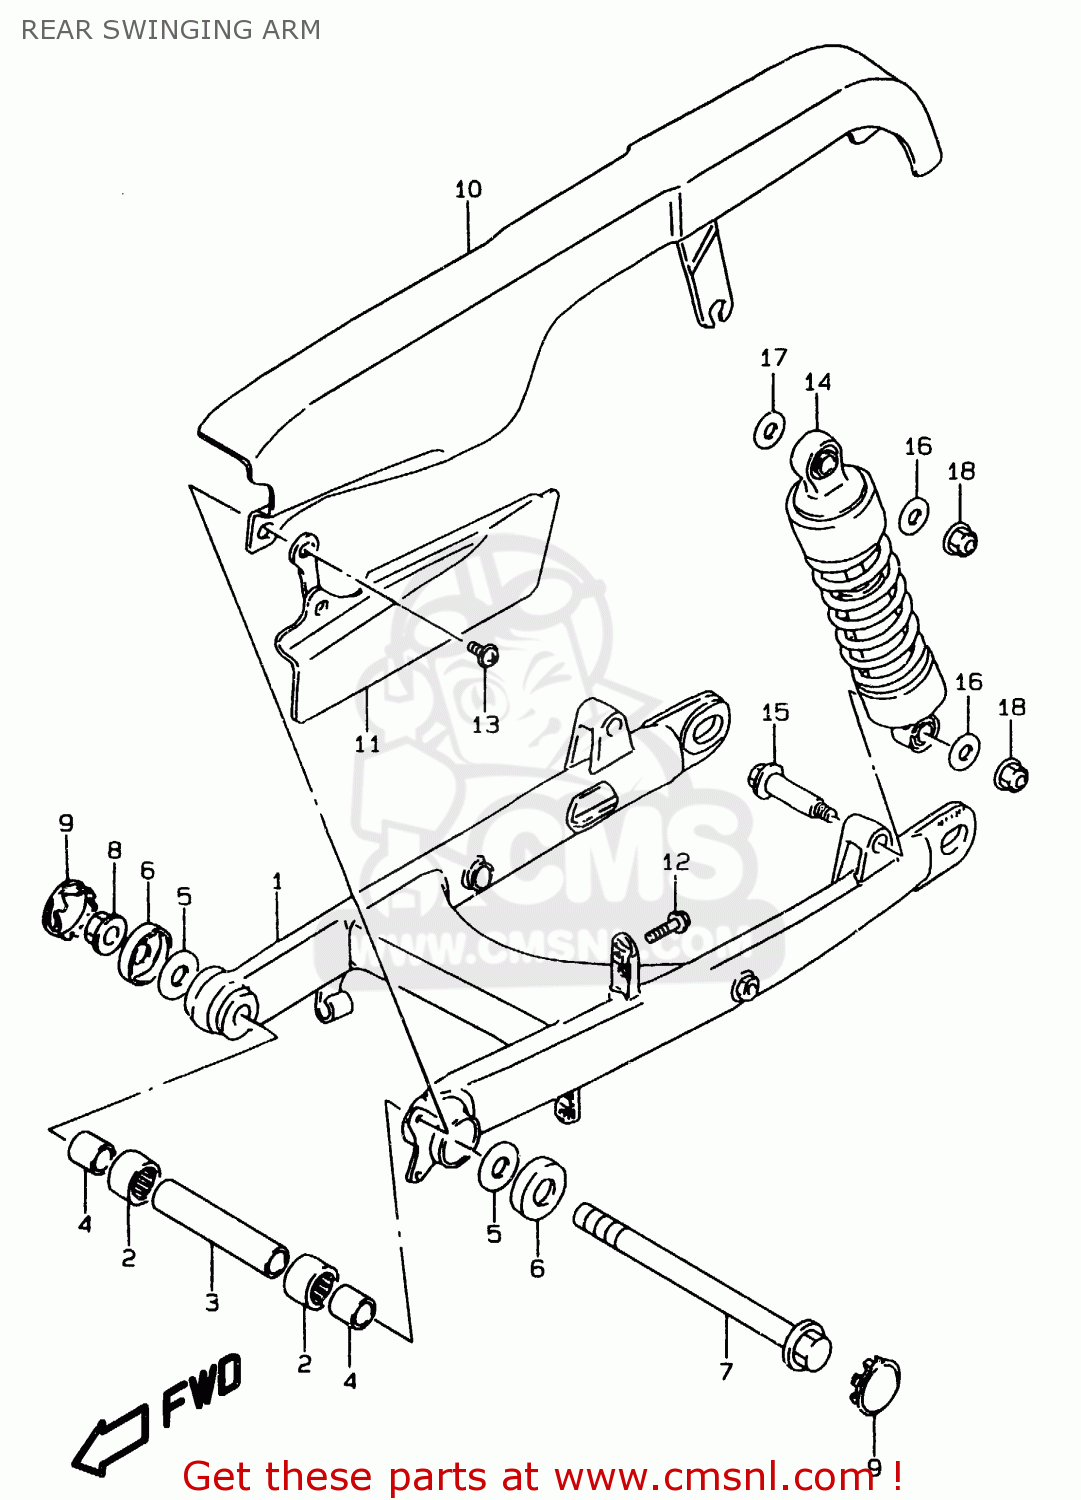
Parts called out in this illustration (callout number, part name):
1	SWINGINGARM,RR
2	BEARING(22X29X30)
3	SPACER,RR SWGARM PIVOT CTR
4	SPACER,RR SWGARM PIVOT
5	WASHER
6	CVR,RR SWGARM DUST SEAL(OD:40)
7	SHAFT,RR SWINGINGARM PIVOT
8	NUT
9	CAP,RR SWINGING ARM PIVOT,R
10	BELT CASE,UPR
11	BELT CASE,LWR
12	BOLT
13	SCREW
14	ABSORBER ASSY,RR SHOCK
15	BOLT,RR SHOCK ABSORBER LWR
16	WASHER(10.5X28X2.3)
17	WASHER(14.5X29X2.3)
18	NUT
